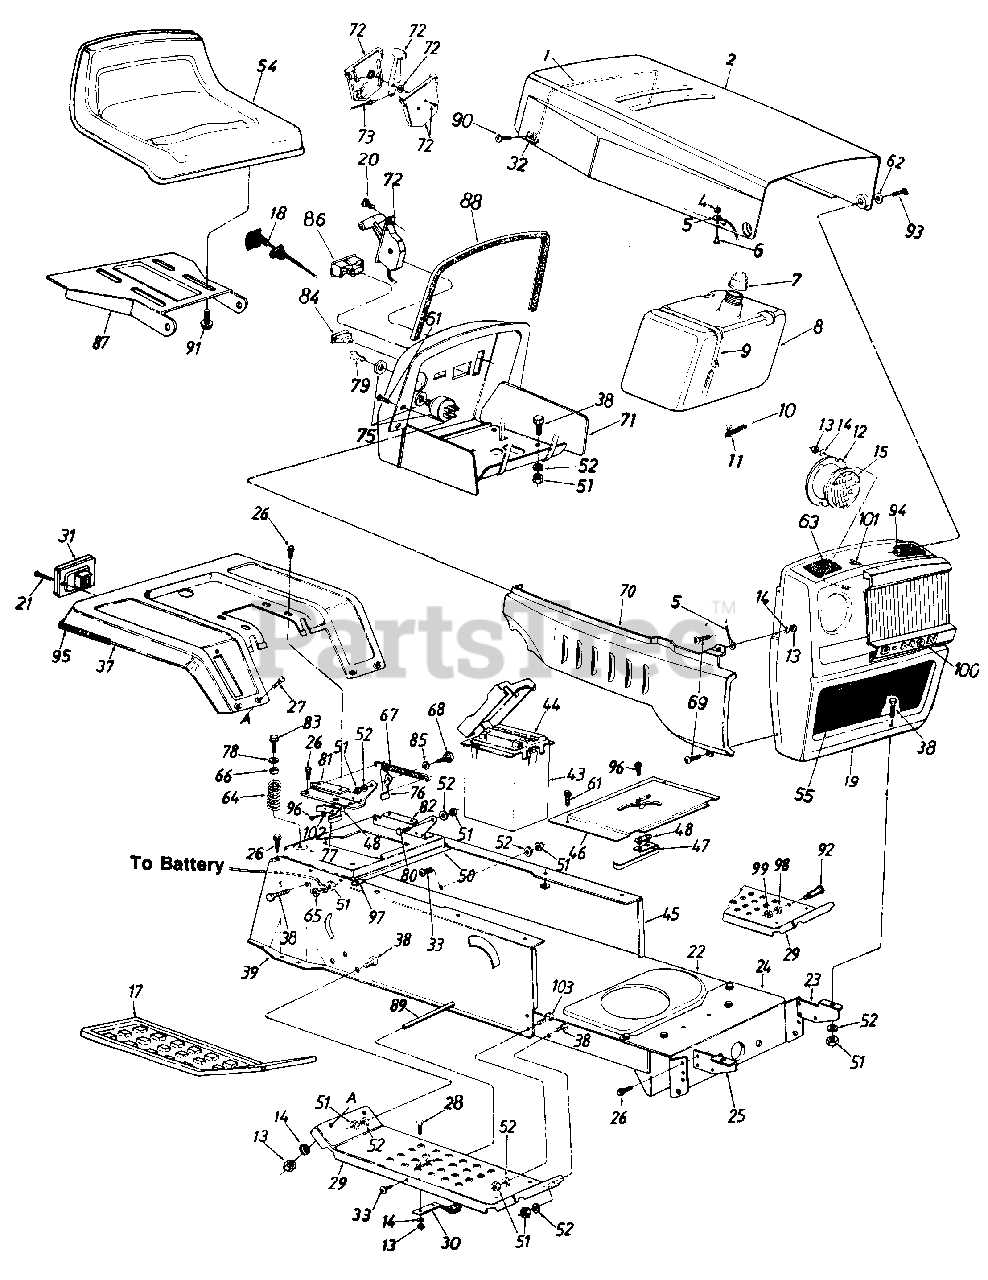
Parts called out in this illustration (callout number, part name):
1	Hood Spring
5	Hood Stop 7" Lg.
6	Pop Rivet
7	Fuel Cap Gauge
8	Fuel Tank
9	Tie Strap
10	Fuel Line
11	Hose Clamp
12	Headlight Retainer
13	Hex Nut 1/4-20 Thd.
14	L-Wash. 1/4" I.D.
15	Headlight
17	Foot Pad L.H.
18	Choke Control 29" Lg.
21	Truss AB-Tap Scr. #6 x .62" Lg.
22	Lower Frame
23	Grille Mount Brkt.
24	Front Pivot Brkt.
27	Carriage Bolt 1/4-20 x 2.0"
28	Carriage Bolt 1/4-20 x .62"
29	Running Board
30	Blade Brake Ass'y.
31	Taillight
32	lood Spring Retainer
33	Truss Mach. Scr. 5/16-18 x .75" Lg.
37	Fender
38	Hex Bolt 5/16-18 x .75" Lg.
39	R.H. Side Frame
43	Battery Box w/Cover
44	12-V Battery
45	L.H. Side Frame
46	Shift Cover
47	Reverse Safety Switch
48	Insulator Nut Plate
50	Hitch Plate
51	Hex Nut 5/16-18 Thd.
52	L-Wash. 5/16" I.D.
54	Seat Ass'y.
55	Grille Insert
61	Truss Mach. Tap Scr. #10 x .50" Lg.
62	Washer .39" I.D. x .62" O.D.
63	Foam Strip 3/8 x 1-1/8 x 11/z
64	Compression Spring
65	Ext. L-Wash. 5/16" I.D.
66	Bushing
67	Ext. Spring 5.31" Lg.
68	Shld. Bolt .437" Dia. x .268"
69	Truss Hd. Scr. 1/4-20 x .75"
70	R.H. Grille Side Panel
71	Dash Panel Ass'y.
72	Throttle Control Box Ass'y.
73	Throttle Control Wire
75	Ignition Switch
76	Seat Lift Bracket
77	Spring Switch
78	Fl-Wash. .344" I.D.
79	Ignition Key
80	Shld. Bolt .437" Dia. x .162"
81	Seat Pivot Brkt. Support R.H.
82	Seat Pivot Brkt. Support L.H.
83	Hex Hd. Tap Scr. 5/16-18 x 1" Lg.
84	Light Switch
85	Spr-Wash. .445" I.D. x .75" O.D.
86	Ammeter
87	Seat Pivot Bracket
88	Molding Strip 27" Lg.
89	Running Board Rod
90	Self-Tap Scr. .5" Lg.
91	Hex Wash. Hd. Tap Scr. 3/8-16 x .75" Lg.
92	Shld. Bolt .50" Dia. x .84"
93	Shld. Bolt .375 Dia. x .125
94	Hex L-Nut 1/4-28 Thd.
95	Trim Strip 81"
96	Hex Wash. Hd. AB-Tap Scr. #8 x .50" Lg.
97	Speed Nut #10Z
98	L-Wash. 3/8" I.D.
99	Hex Nut 3/8-16 Thd.
100	Bezel
101	Self-Tap Scr. #8 x .5" Lg.
102	Fiber Washer
103	Truss Hd. Scr. 5/16-18 x 1.0" Lg.
